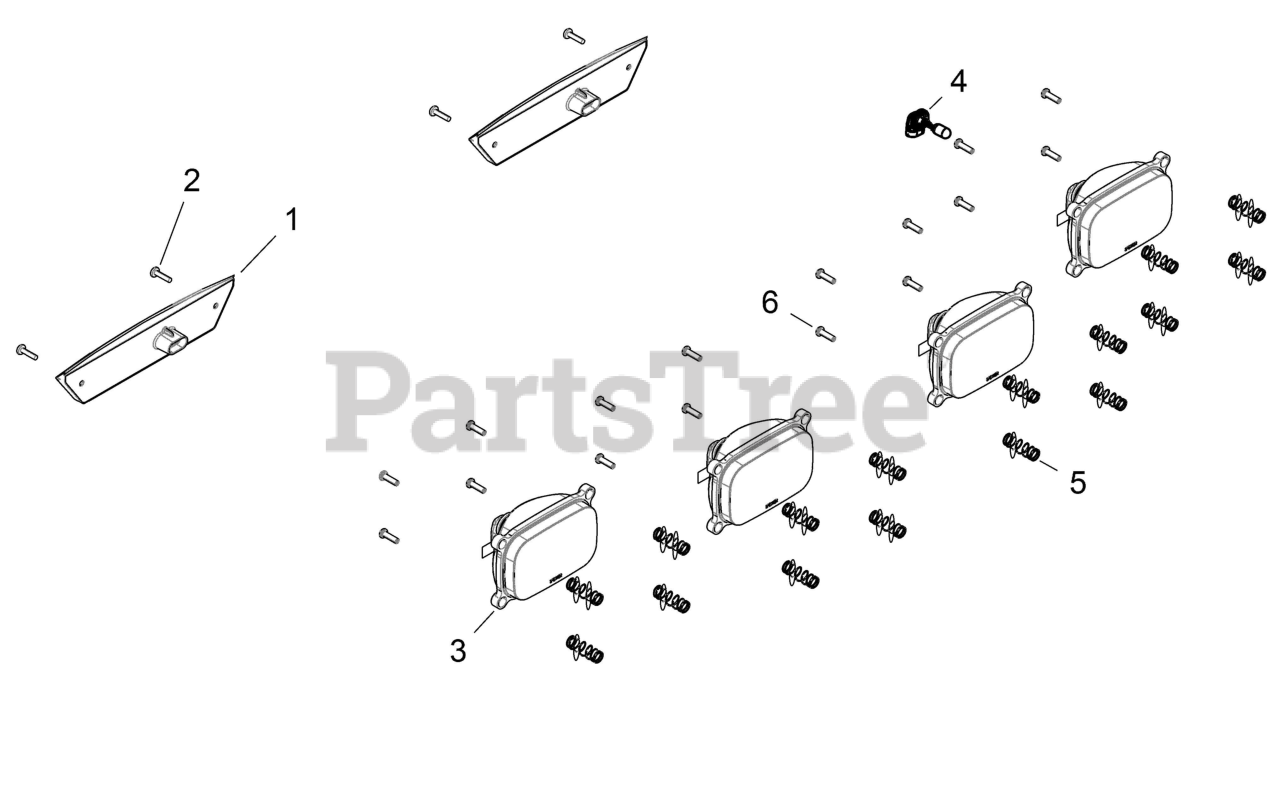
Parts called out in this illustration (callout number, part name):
1	ASM-TAILLIGHT
3	ASM-HEADLIGHT
5	SPRING, HEADLIGHT
